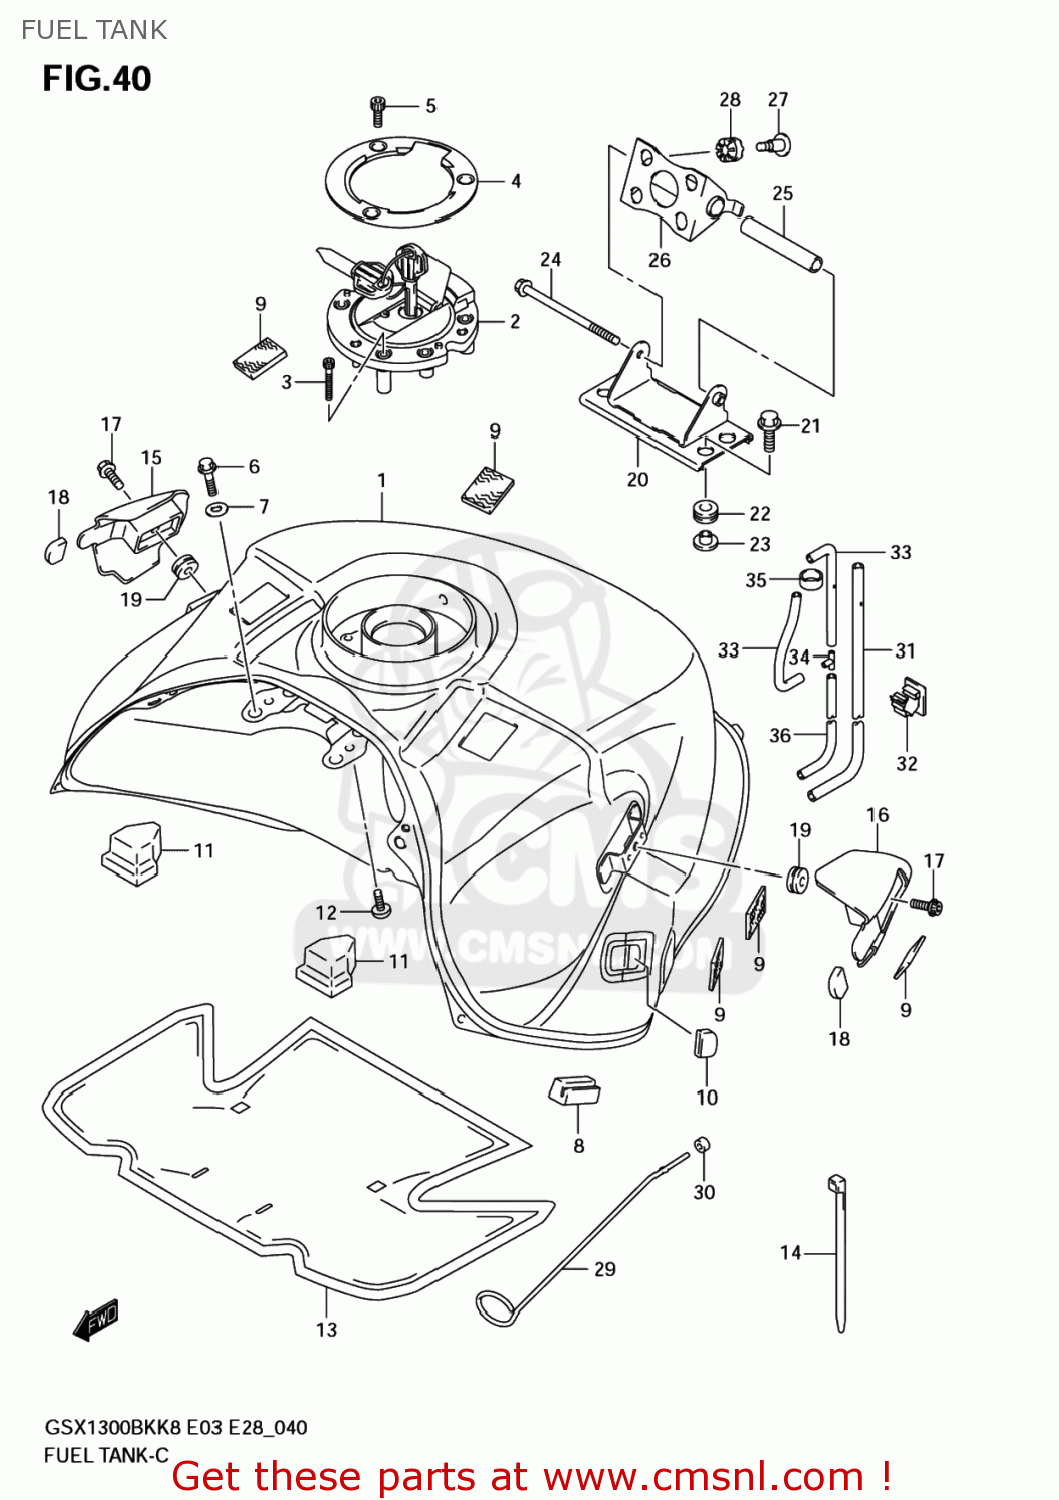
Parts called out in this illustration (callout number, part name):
1	TANK ASSY,FUEL
2	CAP SET,FUEL TANK
3	BOLT
4	COVER,FUEL TANK CAP
5	BOLT(5X12)
6	BOLT
7	WASHER(6.5X28X1.6)
8	CUSHION,FUEL TANK SIDE
9	FASTENER
10	GUIDE,FUEL TANK COVER
11	CUSHION,FUEL TANK RR
12	SCREW(6X10)
13	SHIELD,FUEL TANK HEAT
14	CLAMP
15	BRACKET,FUEL TANK COVER,R
16	BRACKET,FUEL TANK COVER,L
17	SCREW(6X10)
18	CUSHION,TANK SIDE COVER
19	CUSHION
20	BRACKET,FUEL TANK NO.2
21	BOLT(6X20)
22	CUSHION
23	WASHER
24	BOLT
25	SPACER,FUEL TANK RR
26	BRACKET,FUEL TANK NO.1
27	SCREW,FUEL TAN
28	CUSHION
29	STAY,FUEL TANK
30	CUSHION
31	HOSE,FUEL TANK WATER DRAIN
32	CLAMP
33	HOSE,TANK BREA
34	JOINT,3 WAY
35	HOSE(13.5X16.5X600)
36	HOSE(5X8.2X600)
